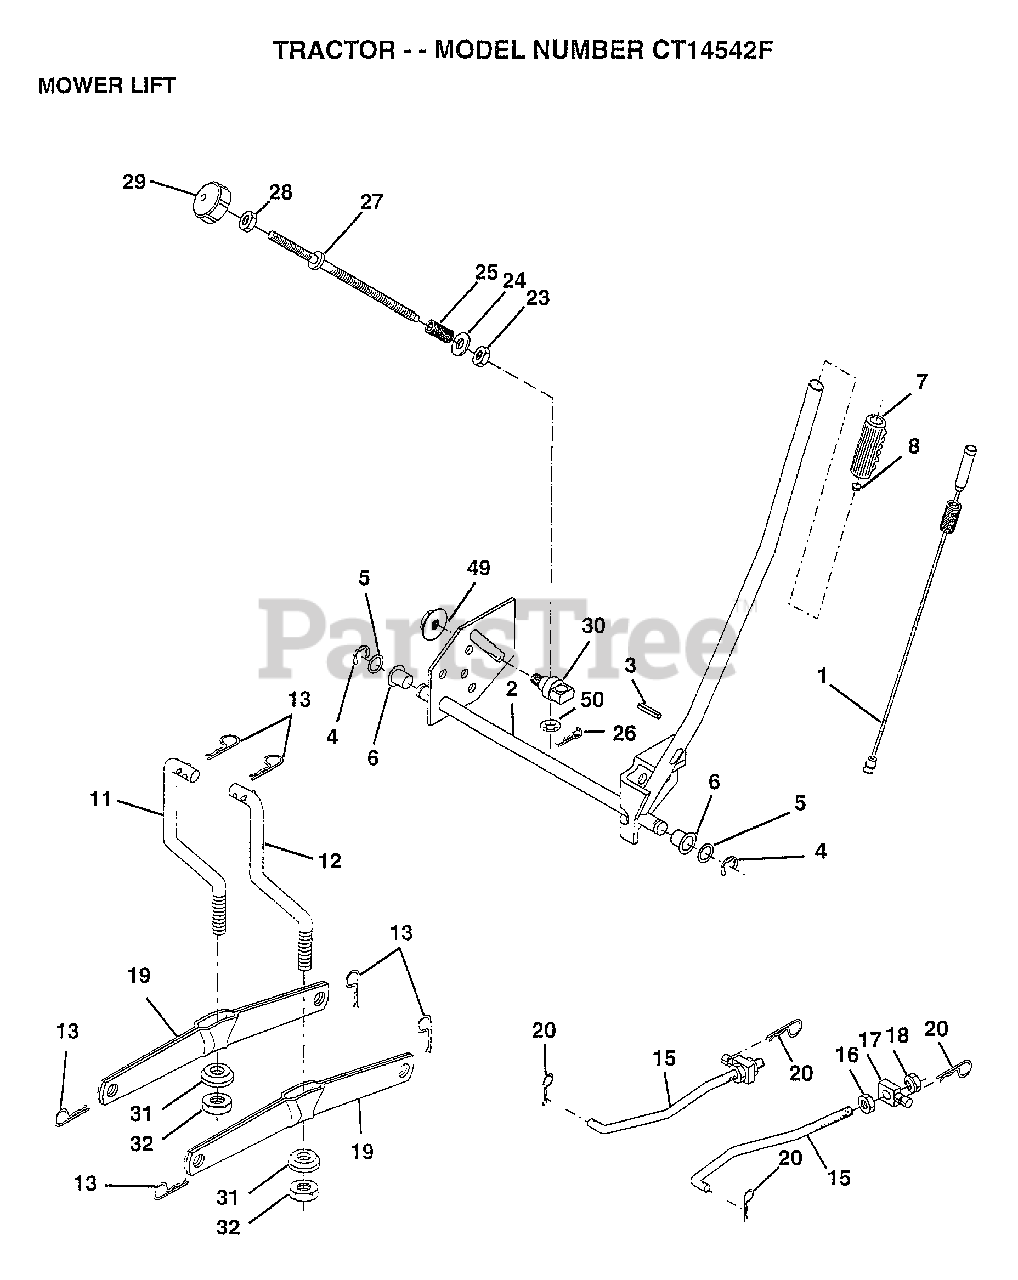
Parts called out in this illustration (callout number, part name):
1	WIRE.ASM.INNER.SP
2	"SHAFT AMS LIFT,RH"
3	PIN GROOVE
5	WASHER
6	NYLON BEARING
7	GRIP
15	LINK.FRONT
16	NUT
17	TRUNION
18	NUT.LK.W/WSH.1/2.
19	ARM SUSP REAR
20	RETAINER.SPRING
23	NUT T
24	WASHER
25	SPRING.COMP.INF.H
27	ROD.ADJ.LIFT
28	NUT
29	KNOB INF 3/8-16
30	TRUNNION
31	BEARING PVT LH
32	NUT.CROWNLOCK.3/8
49	NUT.HXFLG.LOCK.
50	NUT PUSH M
